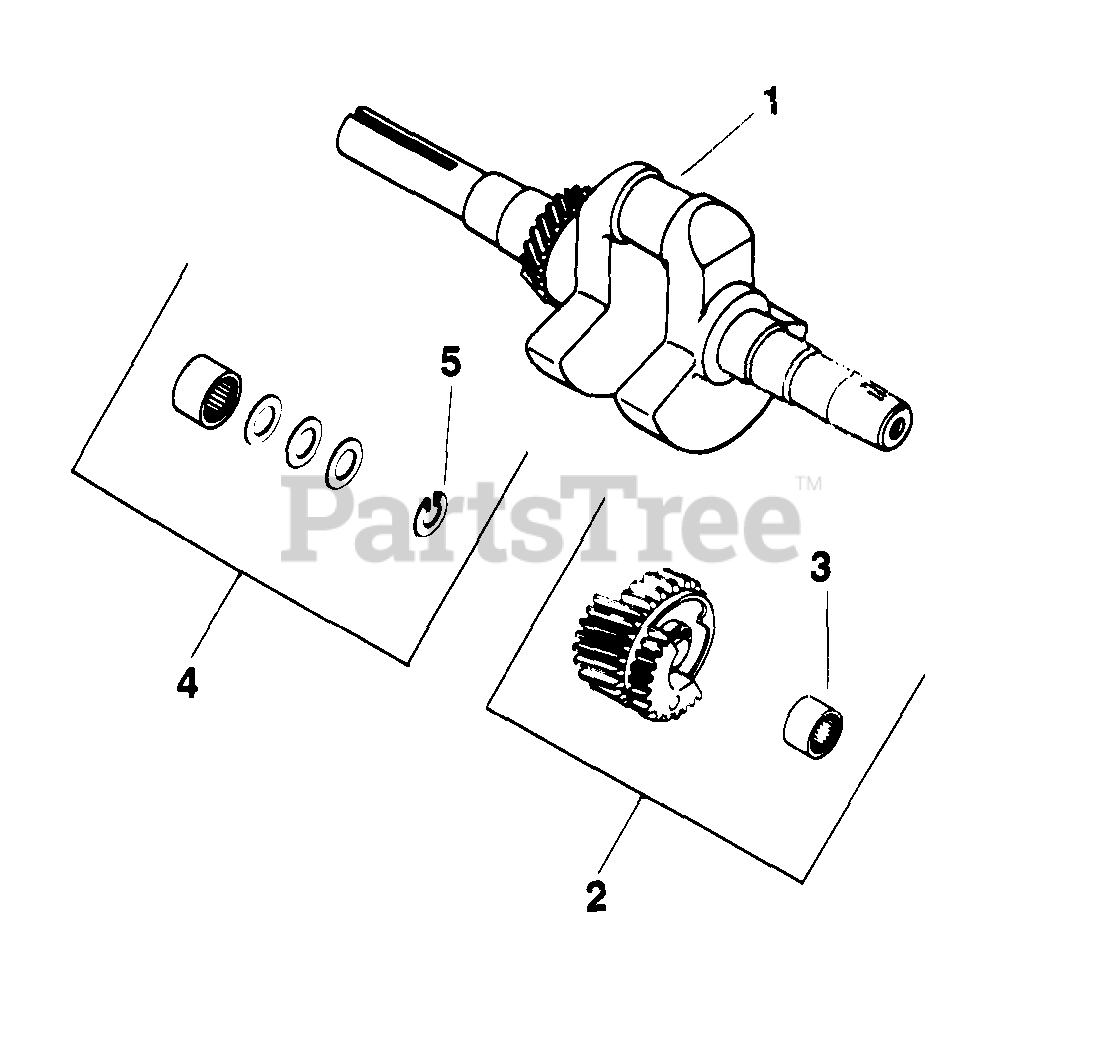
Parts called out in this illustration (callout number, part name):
1	CRANKSHAFT - USE 45 142 21
2	GEAR
4	KIT, SPACER
